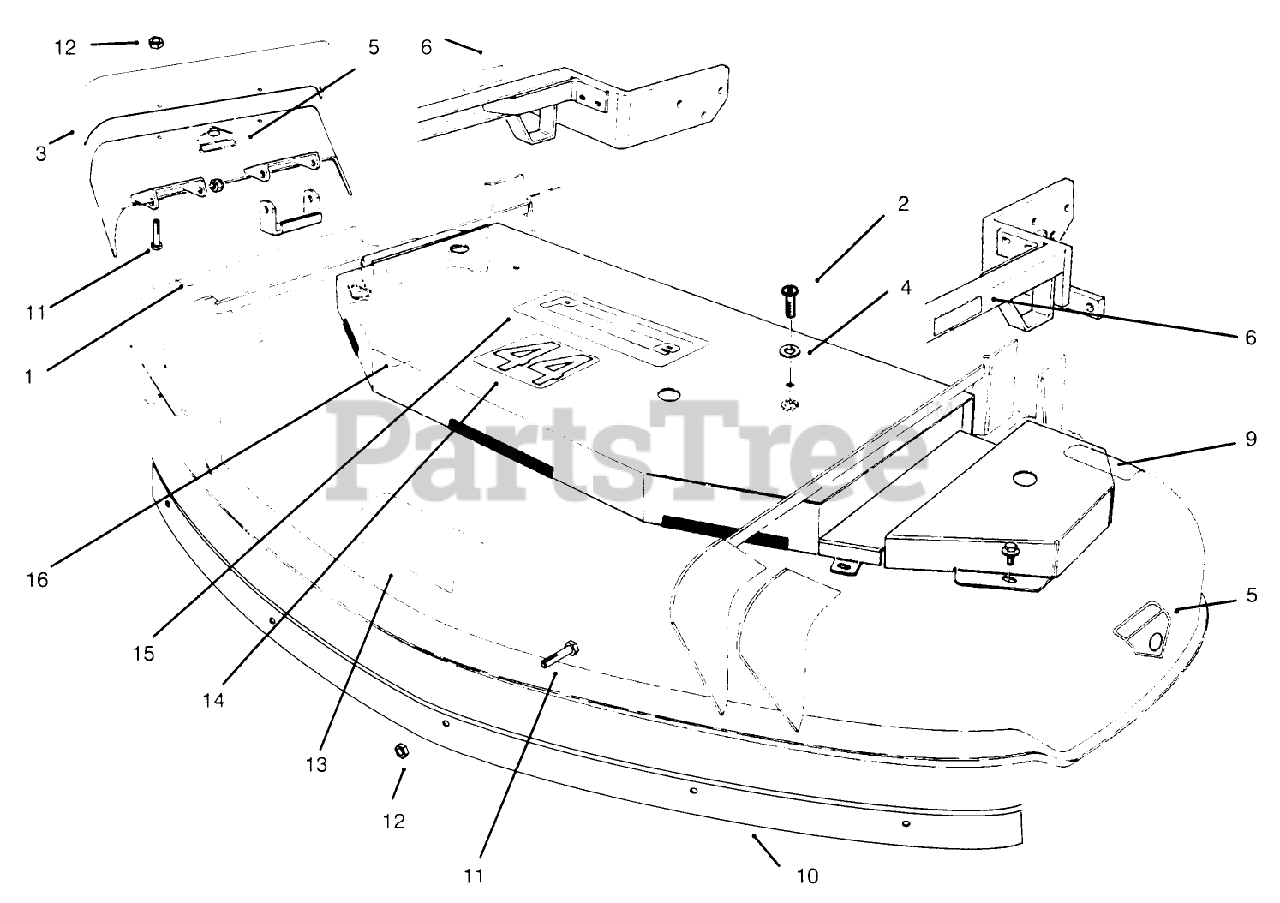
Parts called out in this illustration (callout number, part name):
1	DECAL-WARNING, DEFLECTOR
2	SCREW-HH
3	Guard-Deflector
4	WASHER-FLAT
5	DECAL-DANGER
6	DECAL-HOC
9	DECAL-TORQUE, BLADE BOLT
10	Baffle-Front
11	SCREW-HH
12	NUT-LOCK, NI
13	DECAL-DANGER
14	DECAL-44 INCH
15	DECAL-PROLINE
16	DECAL-DANGER
